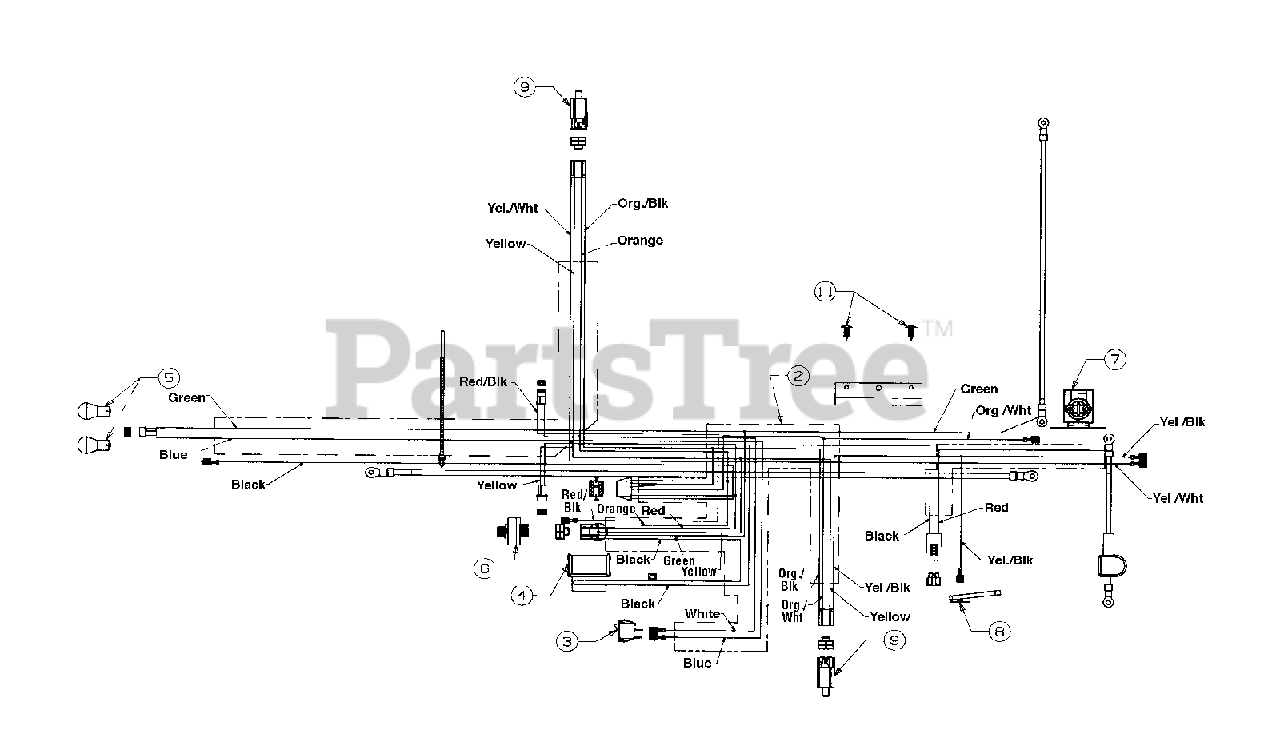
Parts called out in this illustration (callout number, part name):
2	Wire Harness w/Light Switch and Amp
3	Light Switch
4	Ammeter
5	Bulb (Headlight)
6	Ignition Switch
7	Solenoid
8	Safety Switch (Reverse)
9	Safety Switch
11	Ratchet
